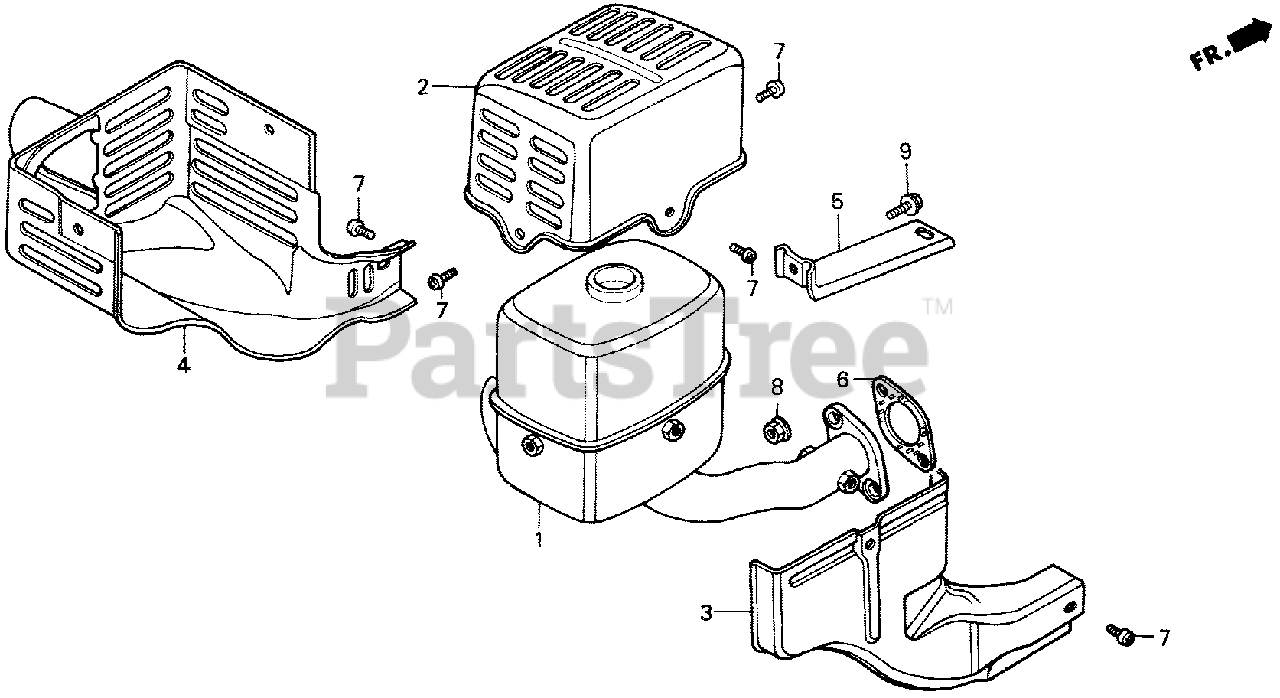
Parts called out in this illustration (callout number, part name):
2	COVER, MUFFLER
3	PROTECTOR, R. MUFFLER
4	PROTECTOR, L. MUFFLER
5	STAY, MUFFLER
6	GASKET, MUFFLER
7	SCREW, PAN (6X6)
8	NUT, FLANGE (8MM)
9	BOLT, FLANGE (6X10)
